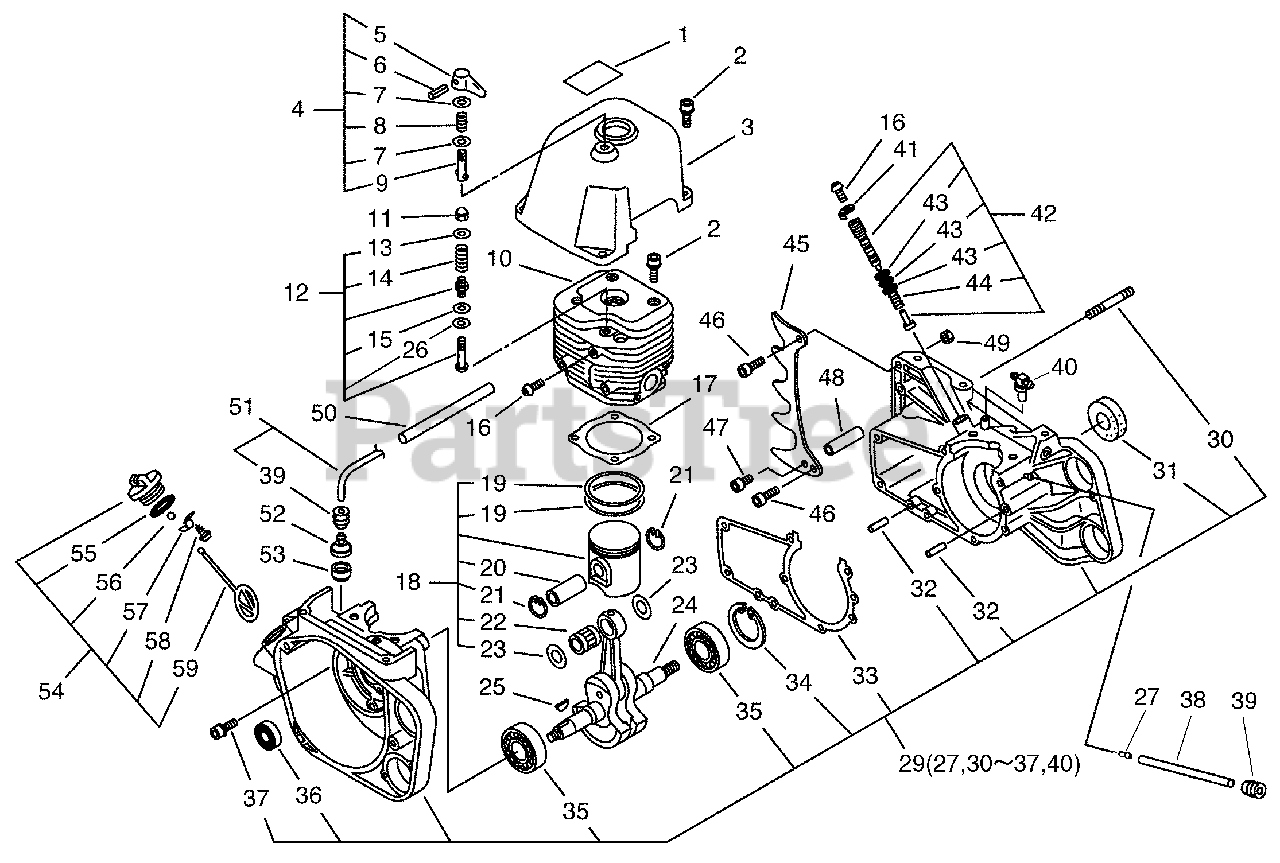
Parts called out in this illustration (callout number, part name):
1	LABEL - DECOMPRESSION
2	BOLT 6×25
3	COVER, CYLINDER
4	LEVER, DECOMPRESSION
5	LEVER, DECOMPRESSION
6	PIN, SPRING - 2×14
7	WASHER, FLAT 5.5×10×0.8
9	SHAFT, DECOMPRESSSION
10	CYLINDER
12	VALVE ASSY, DECOMPRESSION
15	GASKET
16	SCREW 5×10
17	GASKET, CYLINDER
18	PISTON KIT
19	RING, PISTON
20	PIN, PISTON
21	RING, SNAP
22	BEARING, NEEDLE
23	WASHER, THRUST
24	CRANKSHAFT ASSY
24	CRANKSHAFT
25	KEY, WOODRUFF
26	GASKET
27	CONNECTOR
29	CRANKCASE KIT
30	STUD, GUIDE BAR
31	SEAL, OIL
32	PIN, LOCATING 5×10
33	GASKET, CRANKCASE
34	RING, RETAINING - 47
35	BEARING, BALL BB6204
36	SEAL, OIL
37	BOLT 6×30
38	PIPE, FUEL 3×6×140 BLACK
40	CONNECTOR ASSY
41	WASHER, LOCK
42	AUTO-OILER ASSY
45	SPIKE, BUMPER
46	BOLT 6×20
47	BOLT 5×14
48	CHAIN CATCHER
49	NUT, LOCK
50	PROTECTOR, TUBE
52	FILTER, OIL
53	OIL FILTER COVER
54	CAP ASSY, OIL TANK
55	O-RING 25 MM
56	VALVE, BALL
57	RETAINER, CONNECTOR
58	SCREW, TAPPING 3×8
59	CONNECTOR, CAP L= 60 MM
